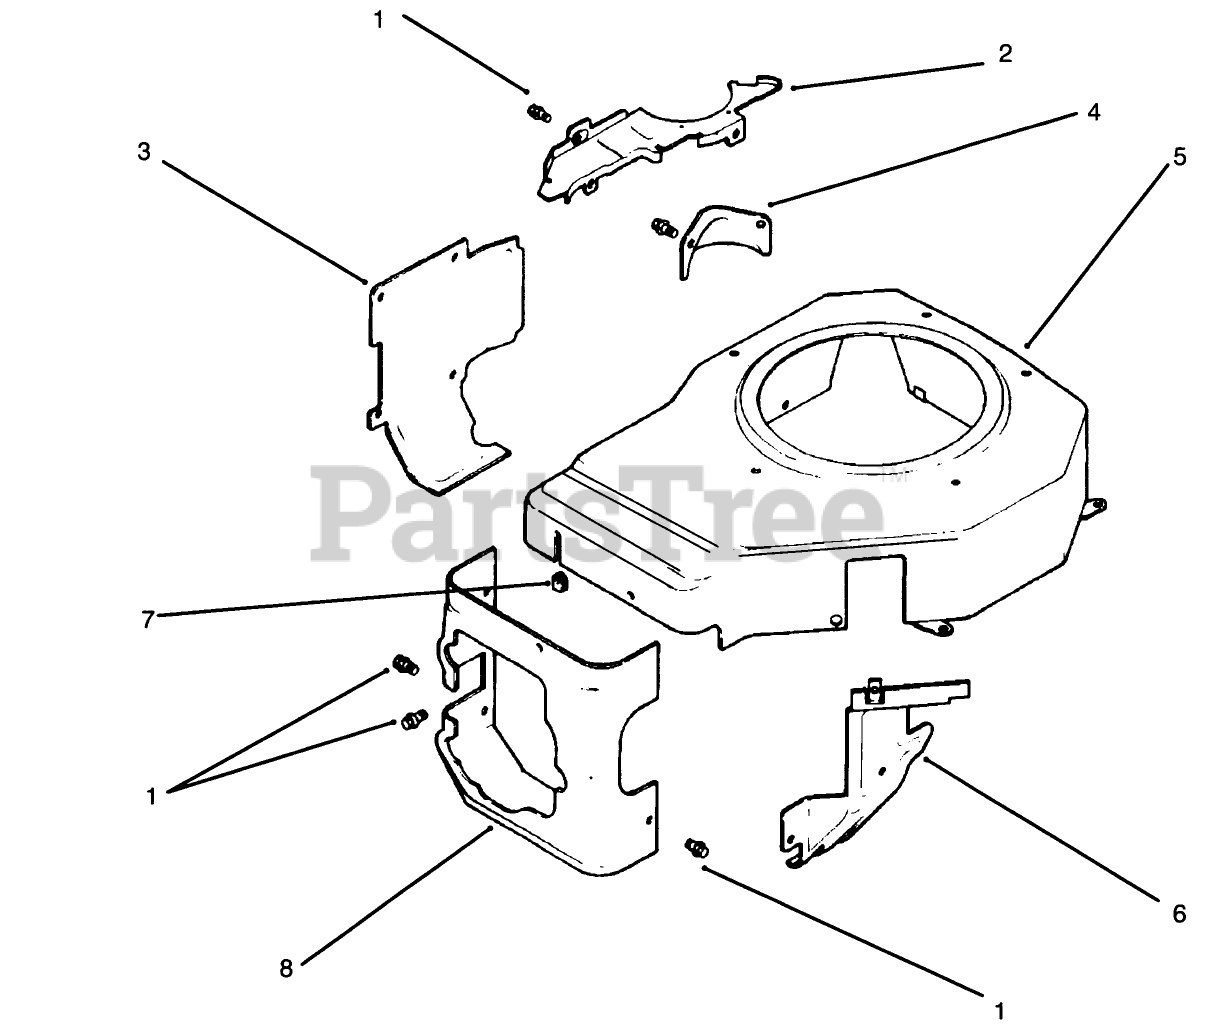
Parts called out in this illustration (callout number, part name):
2	Plate-Blower Housing (Only On: 72042,72043,72062,72063)
3	Baffle-Cylinder Barrel (Only On: 72042, 72063, 72062, 72043)
4	Cover-Starter
5	Cover-Housing
6	Baffle-Carburetor (Only On: 72042, 72043, 72062, 72063)
7	Grommet-Blower Housing (Only On: 72042, 72043, 72062, 72063)
8	Baffle-Cylinder Head
